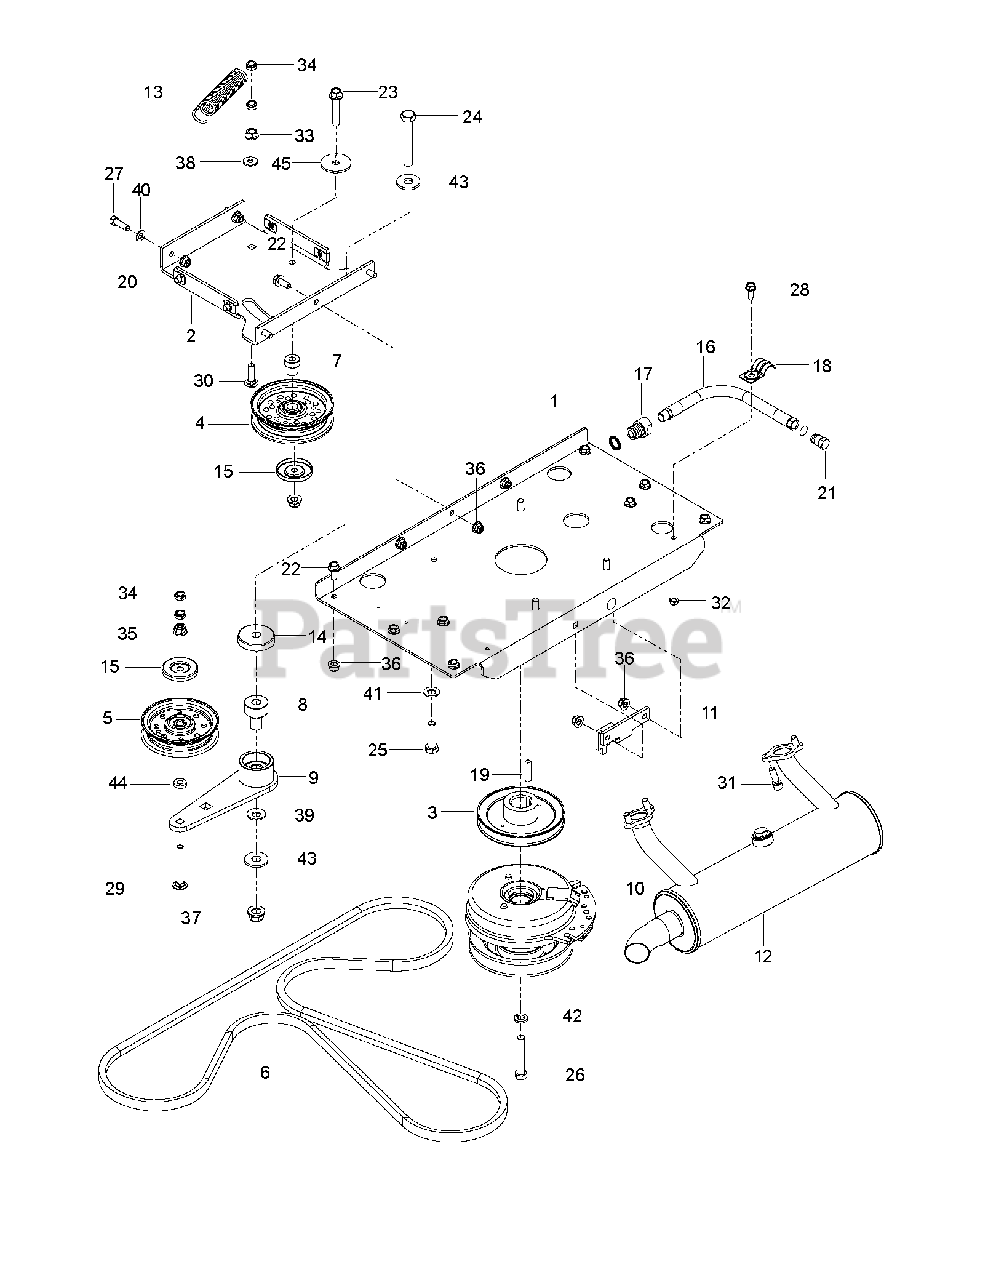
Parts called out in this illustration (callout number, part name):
1	PLATE.PNT.ENGINE.E-DIP
2	PLATE.PNT.IDLER.SUPPORT.E-DIP
3	PULLEY, V, 1.125 BORE
4	IDLER PULLEY
5	PULLEY.IDLER.FLAT.46.PR.DR.
6	BELT, HYDRO, 3400
7	PIVOT, IDLER
8	PIVOT, BEARING
9	ARM, IDLER, STEEL, W/BGS
10	CLUTCH 200 FT LB
11	STOP, CLUTCH, BLACK
12	MUFFLER ASY KOH.EFI.W/O2 SEN
13	SPRING, PUMP
14	SHIELD, DUST
15	DUST SHIELD
16	HOSE.ASSEMBLY.OIL.DRAIN
19	KEY, 1/4 SQ X 1 1/4
20	U-CLIP 5/16-18 NUT RETAINER
21	PLUG OIL DRAIN
22	HHFS 5/16-18 X 3/4
23	HHFS 3/8-16 X 2.0 GD 5
24	HCS 1/2-13 X 3-1/4 GD 5 ZD
25	SCREW 3/8-16X1
26	CLUTCH BOLT7/16-20X2.5 GR596HR
27	BOLT.FIN.HEX.5/16-18UNC X 1.00
28	BOLT
29	BOLT
30	BOLT.3/8-14X1.25
31	SCREW.SOCKET HD.5/16-1
32	JAM NUT 1/4C (2 2 PW01)
33	NUT 3/8C WHIZ
34	NUT HEX 3/8-16 NYLON, THIN
35	NUT 3/8-16 HEX FLG NYLOC ZD
36	5/16-18 NYLOC FLANGE NUT
37	NUT, 1/2-13 HEX FLG NYLOC ZD
38	WASHER 3/8 FLAT
39	CONTACT BELLSPR 1/2
40	WASHER
41	LOCKWASHER
42	WASHER 7/16 LOCK
43	WASHER.9/16 X 1 3/8 X 12 GA.
44	WASHER 3/8 X 3/4 X .187 TK
45	WASHER, 3/8 SPEC
